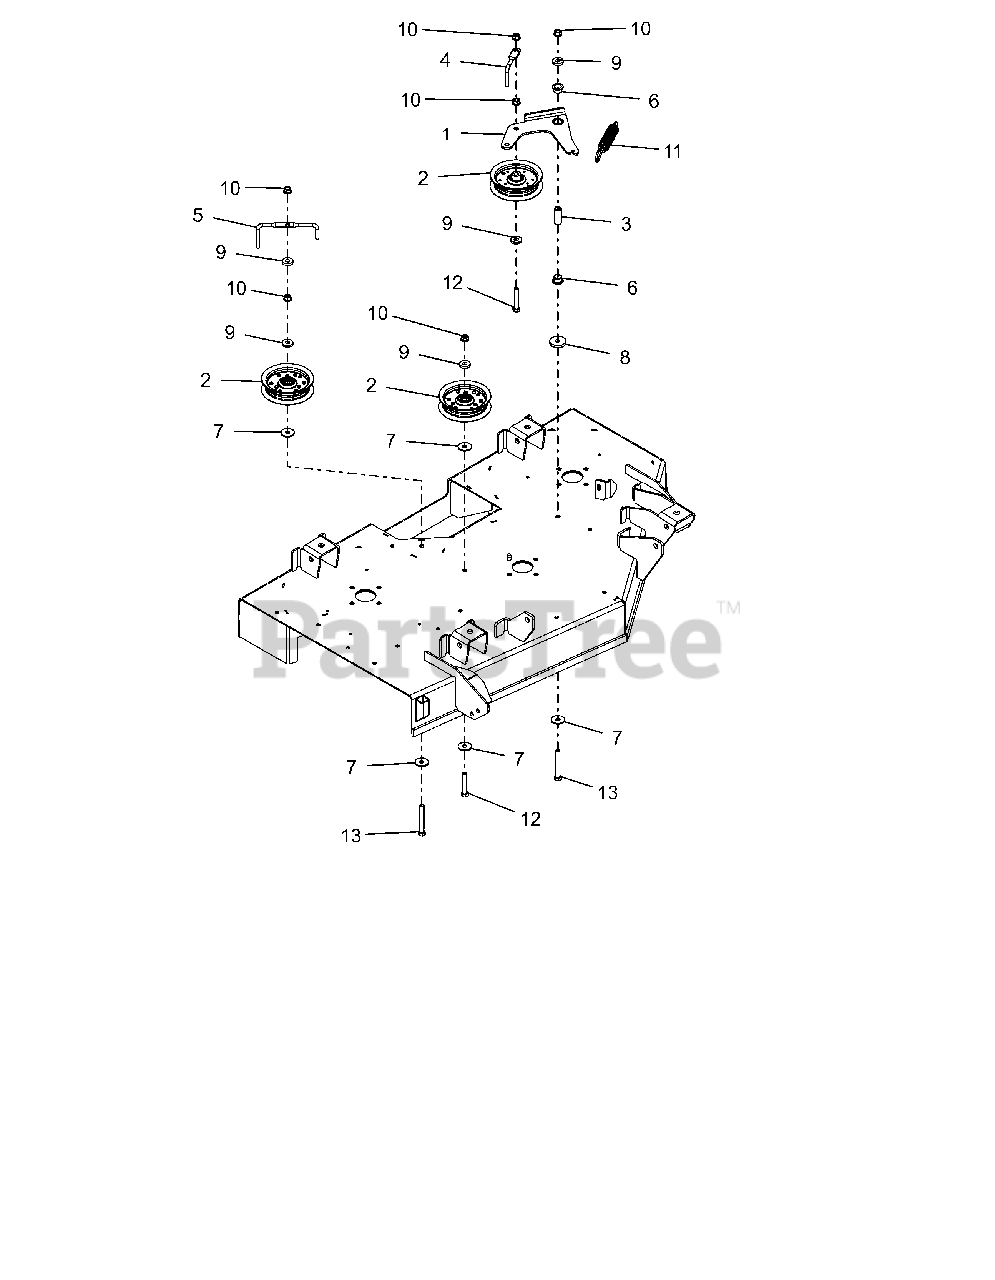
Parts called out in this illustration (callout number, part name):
1	WLDMT, IDLER ARM-42"
2	ASM, IDLER 4"
3	SPACER, .375IDX.625ODX1.66 PM
4	WIREFORM, BELT FINGER
5	WIREFORM, BELT FINGER
6	BSHG-FLG, .625X.750X.500X1.00
7	WSHR FL STL .406X1.25X.10ZC120
8	WSHR, FLT .406X1.50X.245 ZCC
9	WSHR, FLT .406X1.00X.188 ZCC
10	NUT-LK-TOP-FLG .38-16 ZC120
11	SG-TENS .135X.98X6.0 WLD 62
12	BLT,HEX .38-16X2.25 G5 ZCC
13	BLT, HEX .38-16X3.00F G5 ZCC
